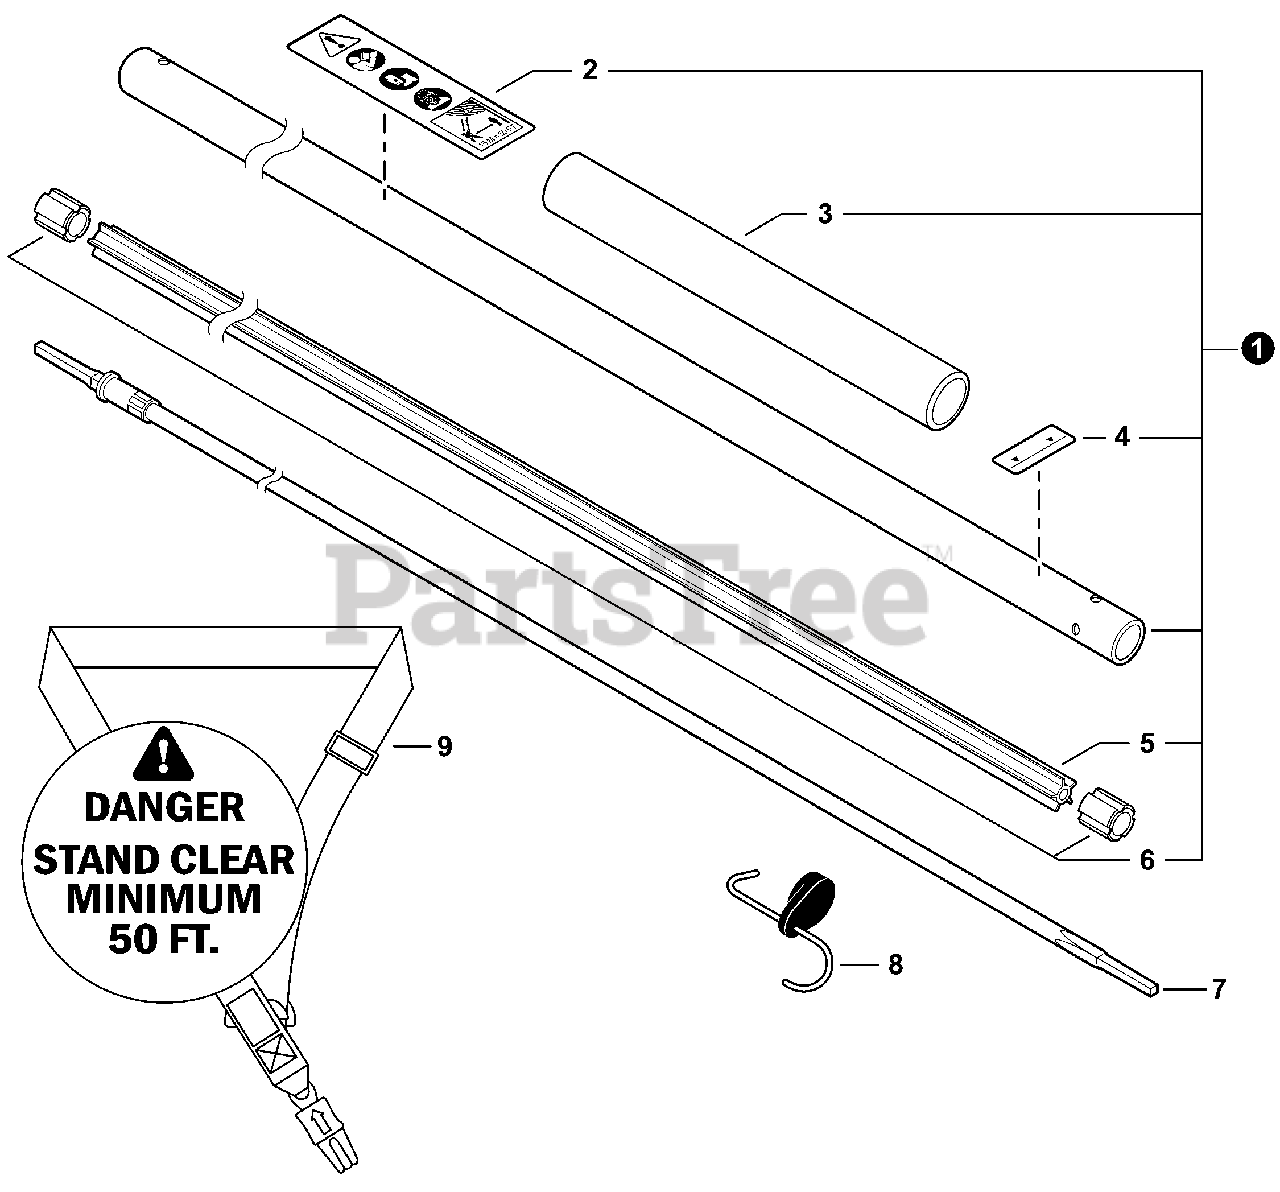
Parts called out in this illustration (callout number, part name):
1	MAIN PIPE ASSY
2	LABEL, CAUTION
3	GRIP, HANDLE
4	LABEL - ALIGNMENT
5	LINER - FLEXIBLE
7	DRIVESHAFT - FLEXIBLE
8	HANGER, ATTACHMENT
9	HARNESS, SHOULDER
